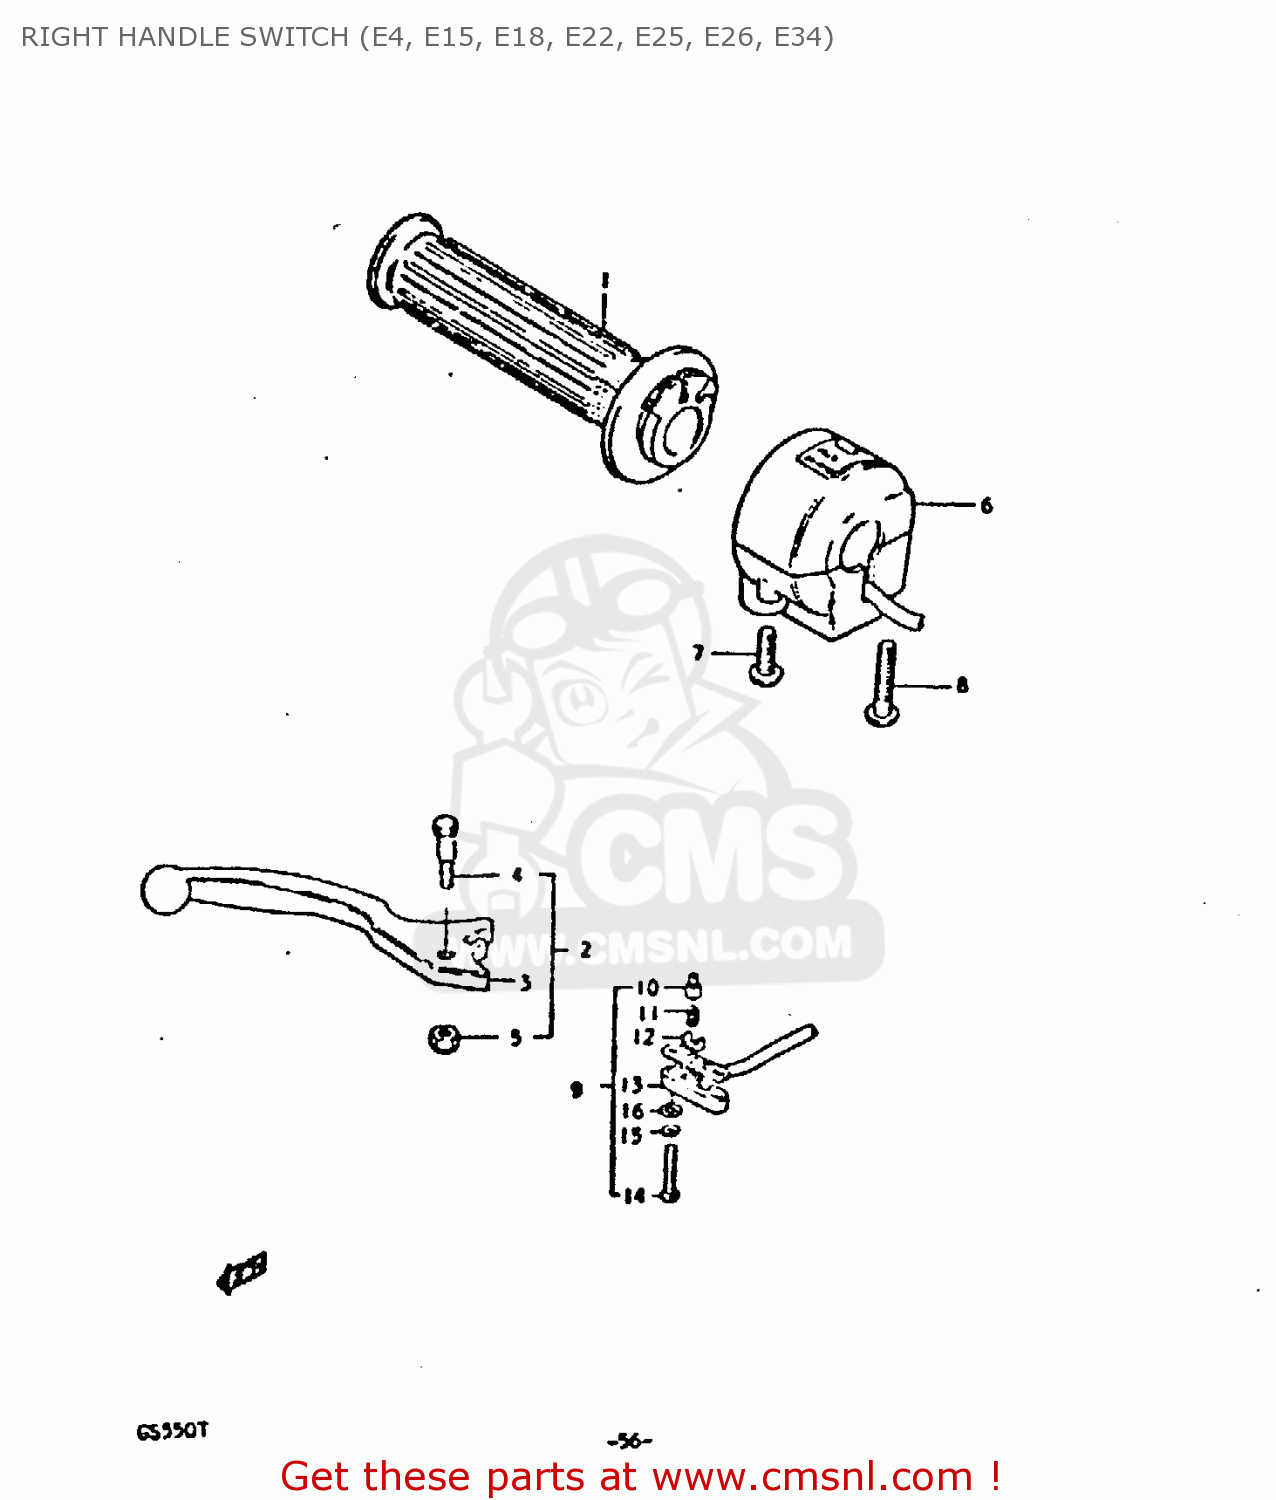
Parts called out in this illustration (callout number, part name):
1	GRIP,THROTTLE
2	LEVER ASSEMBLY,BRAKE
3	LEVER,BRAKE
4	BOLT
5	NUT 6MM
6	SWITCH ASSY, HANDLE RH
7	SCREW
8	SCREW
9	SWITCH ASSEMBLY
10	HOLDER
11	SPRING
12	PLATE
13	COVER,FR BK TERMINAL BASE
14	SCREW
15	LOCK WASHER
16	WASHER
